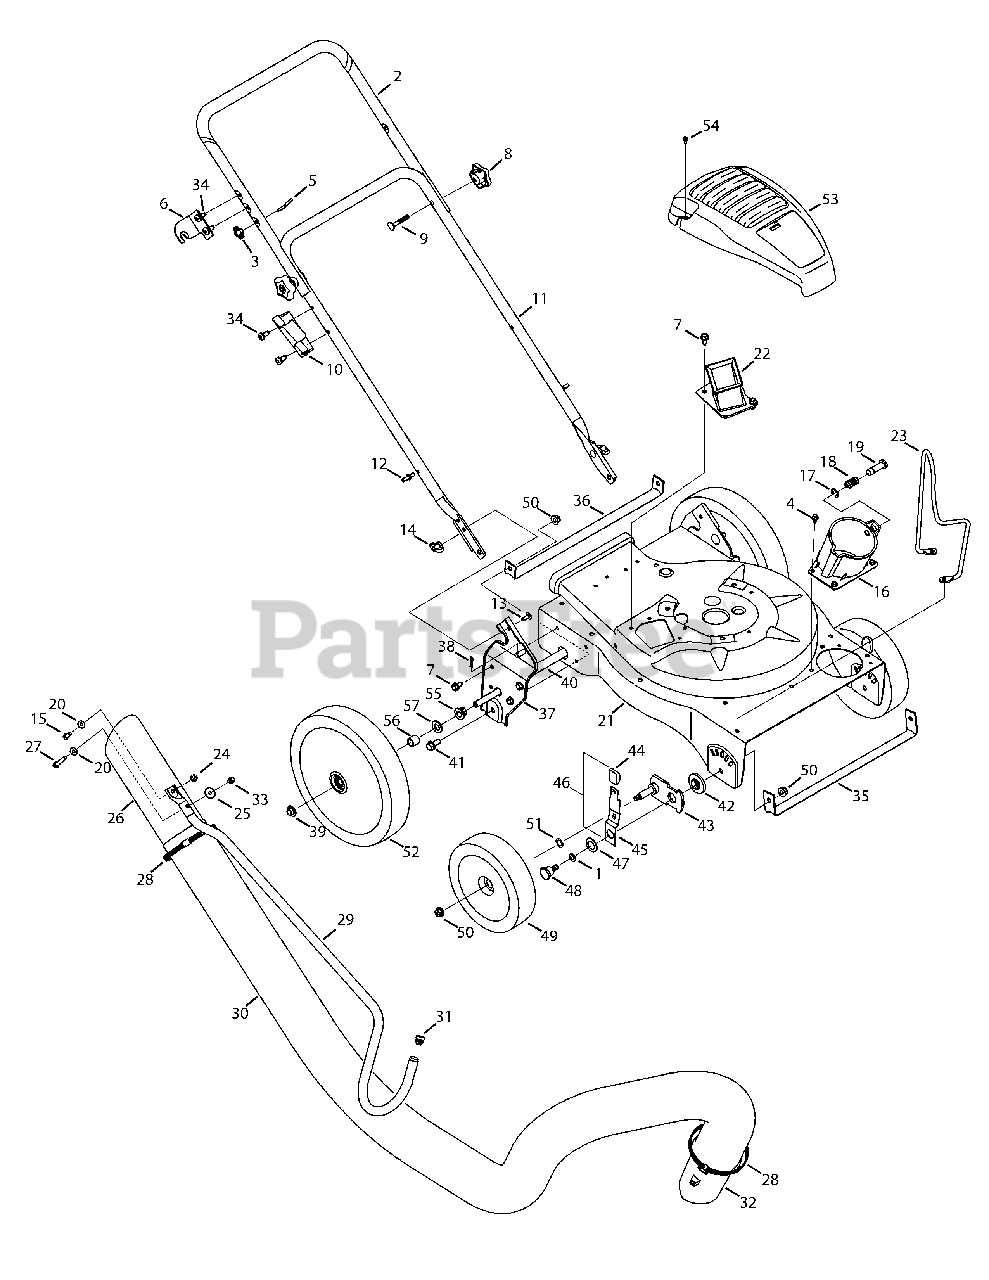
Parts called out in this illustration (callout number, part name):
1	Thrust Washer.375 ID x.70 OD
4	Screw, 1/4-20 x .500
6	Upper Handle Bracket
7	Hex Cap Screw 5/16-12 x.750
9	Carriage Bolt
10	Nozzle Handle Clip
13	Carriage Screw 1/4-20 x.75
14	Wing Nut 1/4-20
15	Hex Cap Screw 1/4-20 x.620
16	Hose Base Adapter Assembly (Incl. Ref.# 17-19)
17	E Ring.500 Dia
18	Compression Spring
19	Clevis Pin
20	Flat Washer.271 ID x.630 OD
21	Upper Flail Housing
22	Chipper Chute Assembly
23	Hose Cradle
24	Flange Lock Nut, 1/4-20
26	Hose Nozzle
27	Hex Cap Screw 1/4-20 x 2.625
28	Adjustment Clamp
30	Vacuum Hose
31	Handle Plug
32	Hose Adapter
33	Cap Lock Nut, 1/4-20
34	TT Screw, 5/16-18 x .750
35	Front Wheel Support Brace
36	Rear Wheel Support Brace
37	Handle Bracket Ass’y RH
37	Handle Brkt Ass’y LH
38	Cotter Pin
41	HHflg, 3/8-16 x .875
42	Height Adjustment Bearing
43	Pivot Arm Assembly
44	Height Adjustment Knob
45	Spring Lever
46	Height Lever Assembly (Incl. Ref.# 44-45)
47	Bell Washer.760 ID x.25 OD
48	Shoulder Screw,.750 x.500
49	Front Wheel
50	Flange Lock Nut, 3/8-16
51	Washer, Wave, .531 x .781 x .013
52	Rear Wheel
53	Engine Shroud
54	Screw, #10-16 x 1.25
55	Brg. Flg, Hex
57	Washer, Flat, .508ID x 1.00 OD
